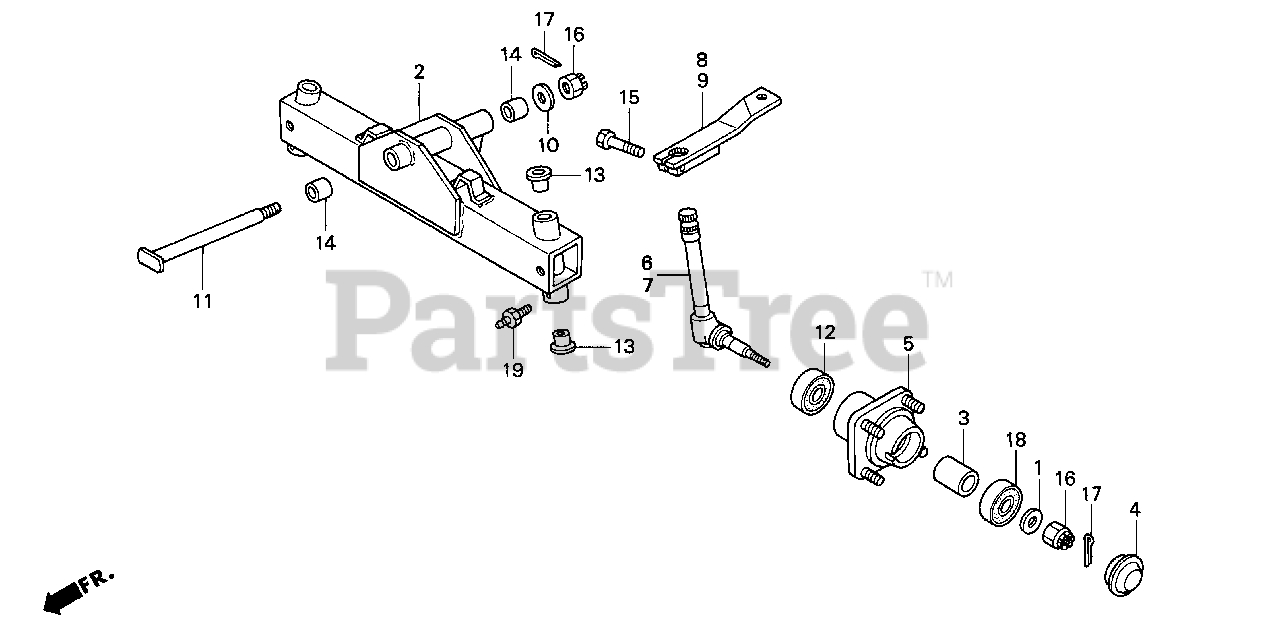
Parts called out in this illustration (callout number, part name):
1	WASHER (14MM)
3	COLLAR, FR. AXLE
4	CAP, FR. HUB
5	HUB, FR. AXLE
6	KNUCKLE, R. FR.
7	KNUCKLE, L. FR.
8	ARM, R. FR. KNUCKLE
9	ARM, L. FR. KNUCKLE
10	WASHER, THRUST (14X30X2.5)
11	PIN, CENTER
12	BEARING, RADIAL BALL (62/22)
13	BUSH (28X25X20)
14	BUSH (20X18X20)
15	BOLT, HEX. (12X40)
16	NUT, CASTLE (14MM)
17	PIN, SPLIT (3.0X45)
18	BEARING, RADIAL BALL (6205UU)
19	NIPPLE, GREASE (A.T6) (M6X1.0)
